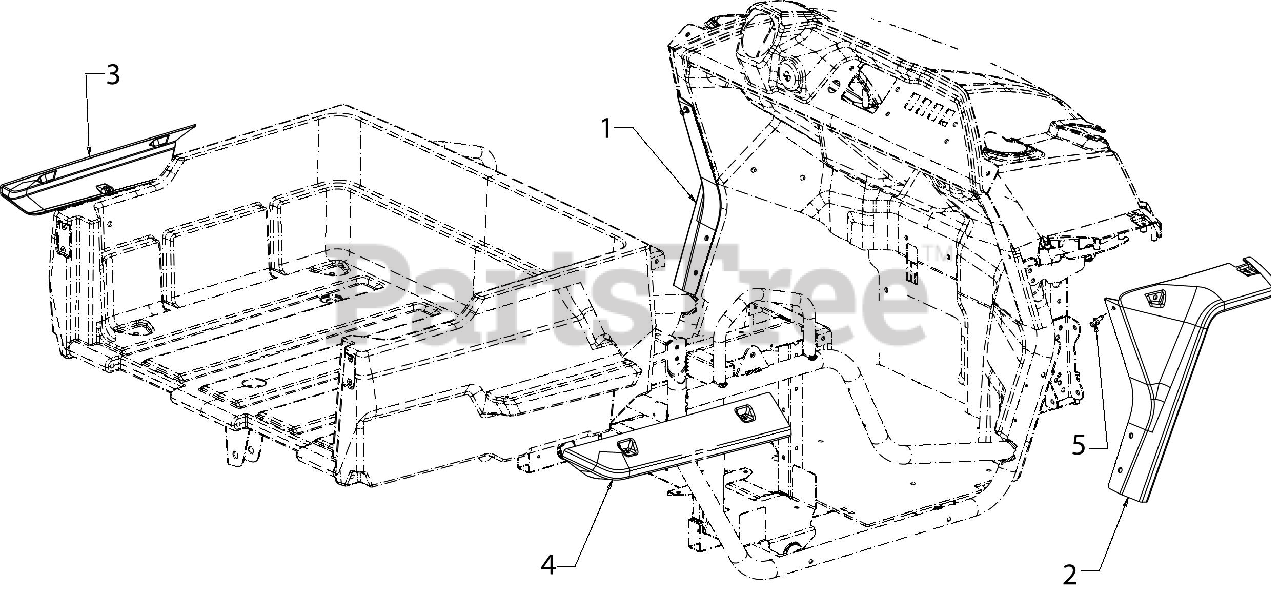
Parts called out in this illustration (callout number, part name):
1	FRONT FENDER (LH)(CAMO)
2	FRONT FENDER (RH)(CAMO)
3	REAR FENDER (LH) (CAMO)
4	REAR FENDER (RH) (CAMO)
5	PLASTIC RIVET
